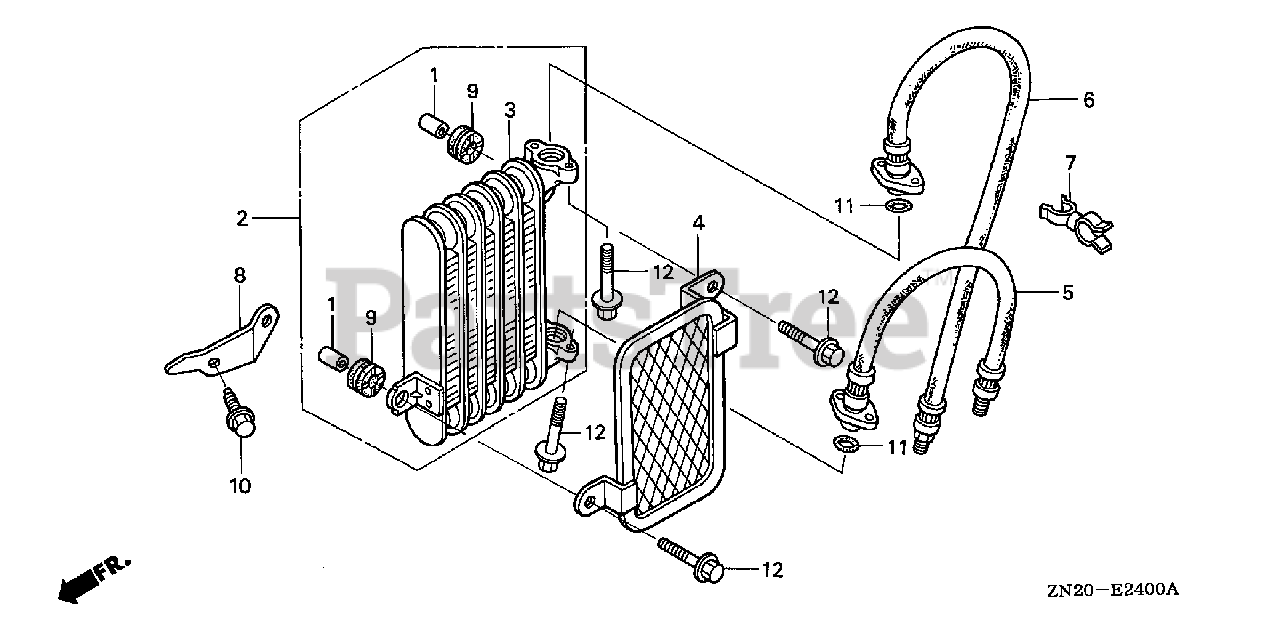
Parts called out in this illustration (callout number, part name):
1	COLLAR (12MM)
2	COOLER ASSY., OIL
3	COOLER, OIL
4	GRILLE, OIL COOLER
5	HOSE A, OIL
6	HOSE B, OIL
7	CLAMP, PIPE (15.5X13)
8	STAY, OIL COOLER
9	RUBBER, RADIATOR MOUNTING
10	BOLT, FLANGE (6X14)
11	O-RING (10X2.6)
12	BOLT, FLANGE (6X22)
